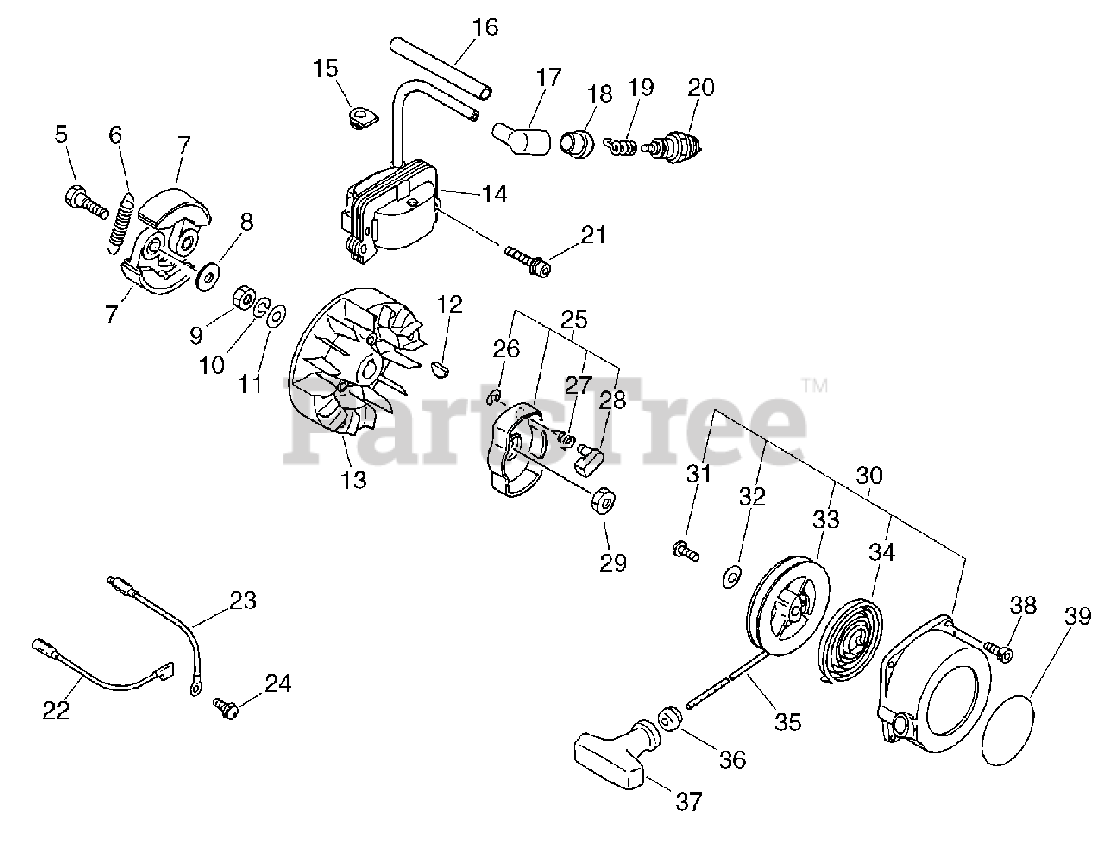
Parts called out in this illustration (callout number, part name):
5	BOLT, CLUTCH M6
6	SPRING, CLUTCH
7	SHOE, CLUTCH
8	WASHER 6.2×19×1.0
9	NUT 8×1.25
10	WASHER, SPRING 8
11	WASHER 8.5×16×1.2
12	KEY, WOODRUFF
13	FLYWHEEL
14	COIL, IGNITION
16	TUBE, PROTECTIVE 6×7×110
17	CAP, SPARK PLUG
18	SEAL, SPARK PLUG
19	TERMINAL, SPARK PLUG
20	SPARK PLUG - BPMR7A
21	BOLT 5×20
22	LEAD - GROUND
22	LEAD - IGNITION
23	LEAD - GROUND
24	SCREW 5×10
25	PAWL ASSY, STARTER
26	E-RING 4
27	SPRING, RETURN
28	PAWL, STARTER
29	NUT 8×1.25
30	STARTER ASSY, RECOIL
33	REEL, ROPE
34	SPRING, RECOIL
35	ROPE, STARTER 4.0×880
36	GUIDE, ROPE
37	GRIP, STARTER
38	BOLT 4×30
39	LABEL, ECHO
